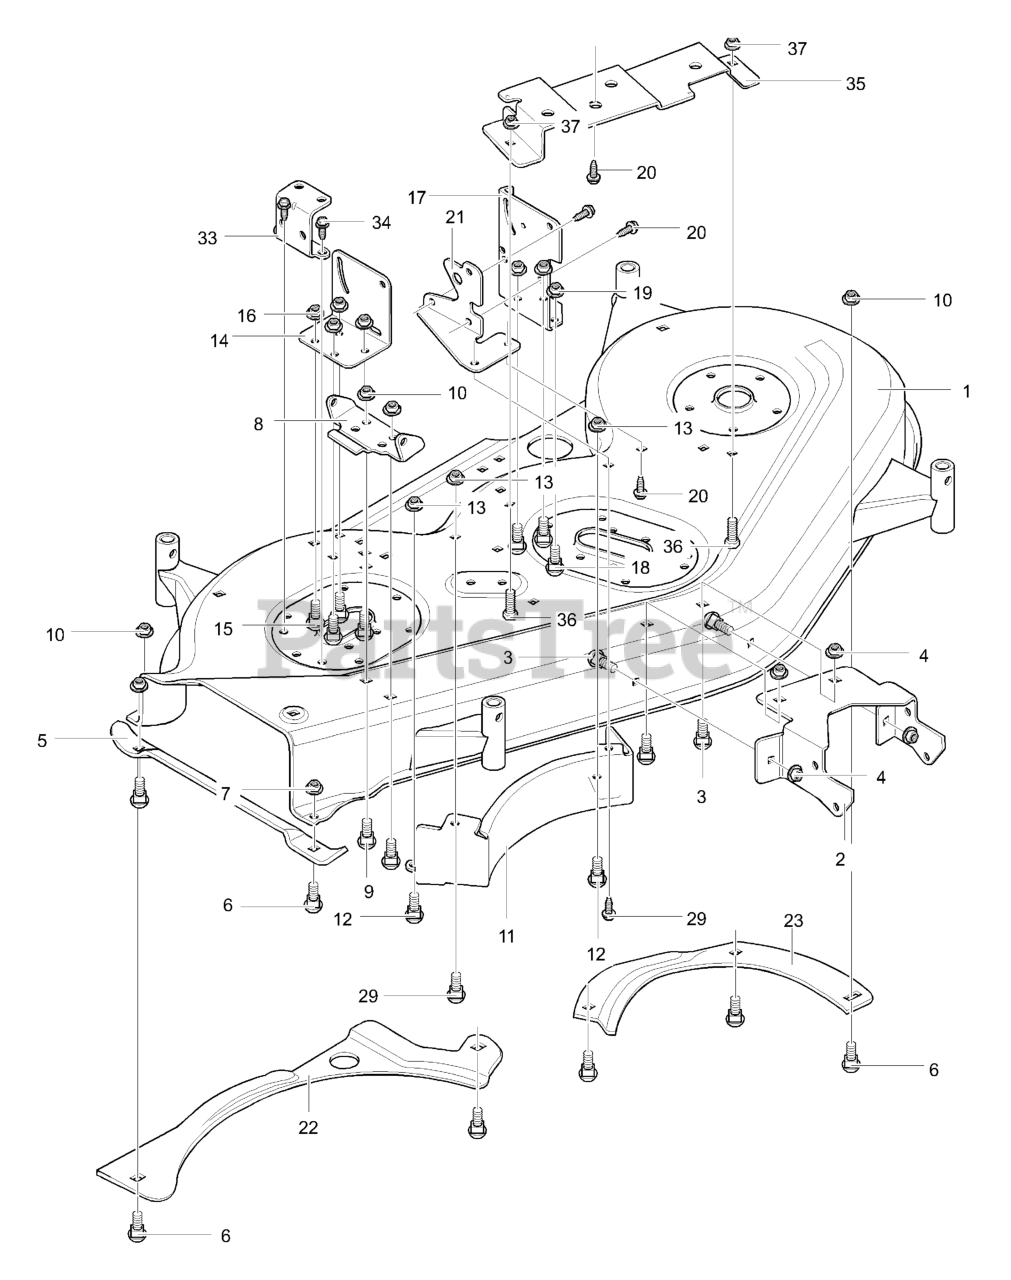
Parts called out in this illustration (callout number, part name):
1	ASSEMBLY, BLADE HOUSING
2	BRACKET, FRONT DECK
3	BOLT, CARRIAGE
4	NUT
5	BRACKET-CHUTE SUPPORT
6	BOLT, CARRIAGE
7	LOCKNUT, FLANGE
8	HINGE, CHUTE BRACKET
9	BOLT, CARRIAGE
10	LOCKNUT, FLANGE
11	BAFFLE, CENTER
12	BOLT, CARRIAGE
13	LOCKNUT, FLANGE
14	BRACKET, RIGHT LIFTER
15	BOLT, CARRIAGE
16	LOCKNUT, FLANGE
17	BRACKET, LIFT LIFTER
18	BOLT, CARRIAGE
19	LOCKNUT, FLANGE
21	BRACE - L.H. LIFTER
22	BAFFLE, RIGHT BOTTOM
23	BAFFLES, LEFT BOTTOM
33	BRACKET, PULLEY COVER
35	BRKT, BRAKE MTG
36	BOLT, CARRIAGE
37	LOCKNUT, FLANGE
